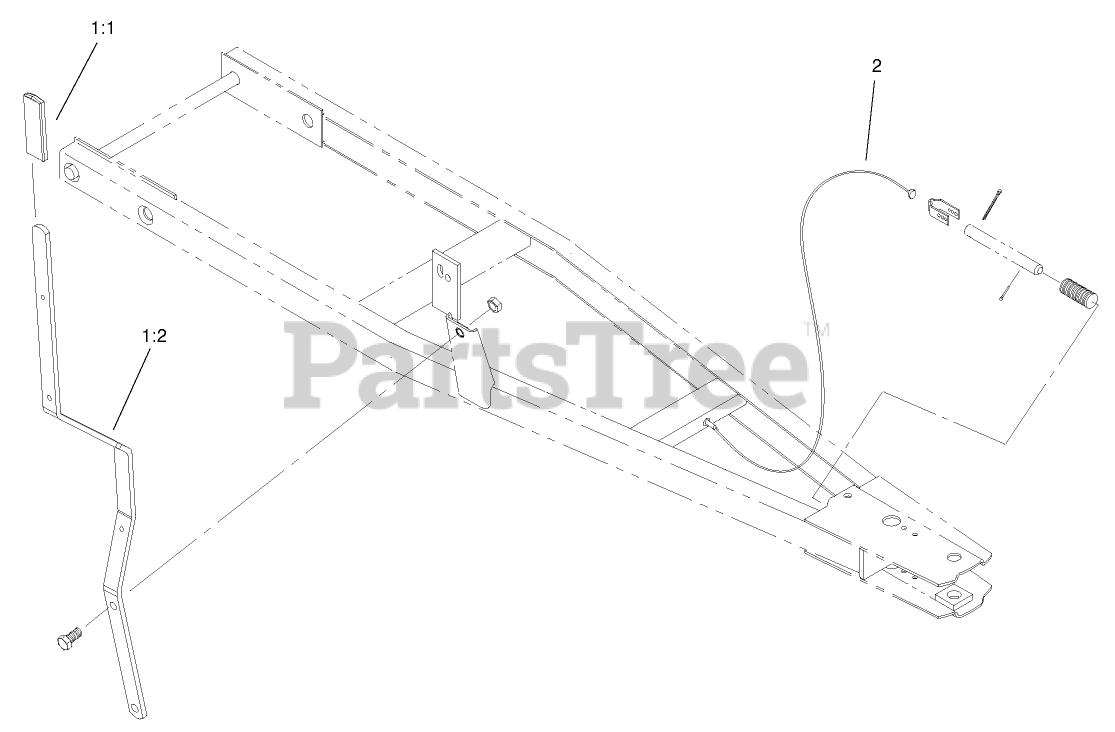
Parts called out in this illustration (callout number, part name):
1:1	GRIP
1:2	LEVER-INDEX
2	CABLE-TENSION
